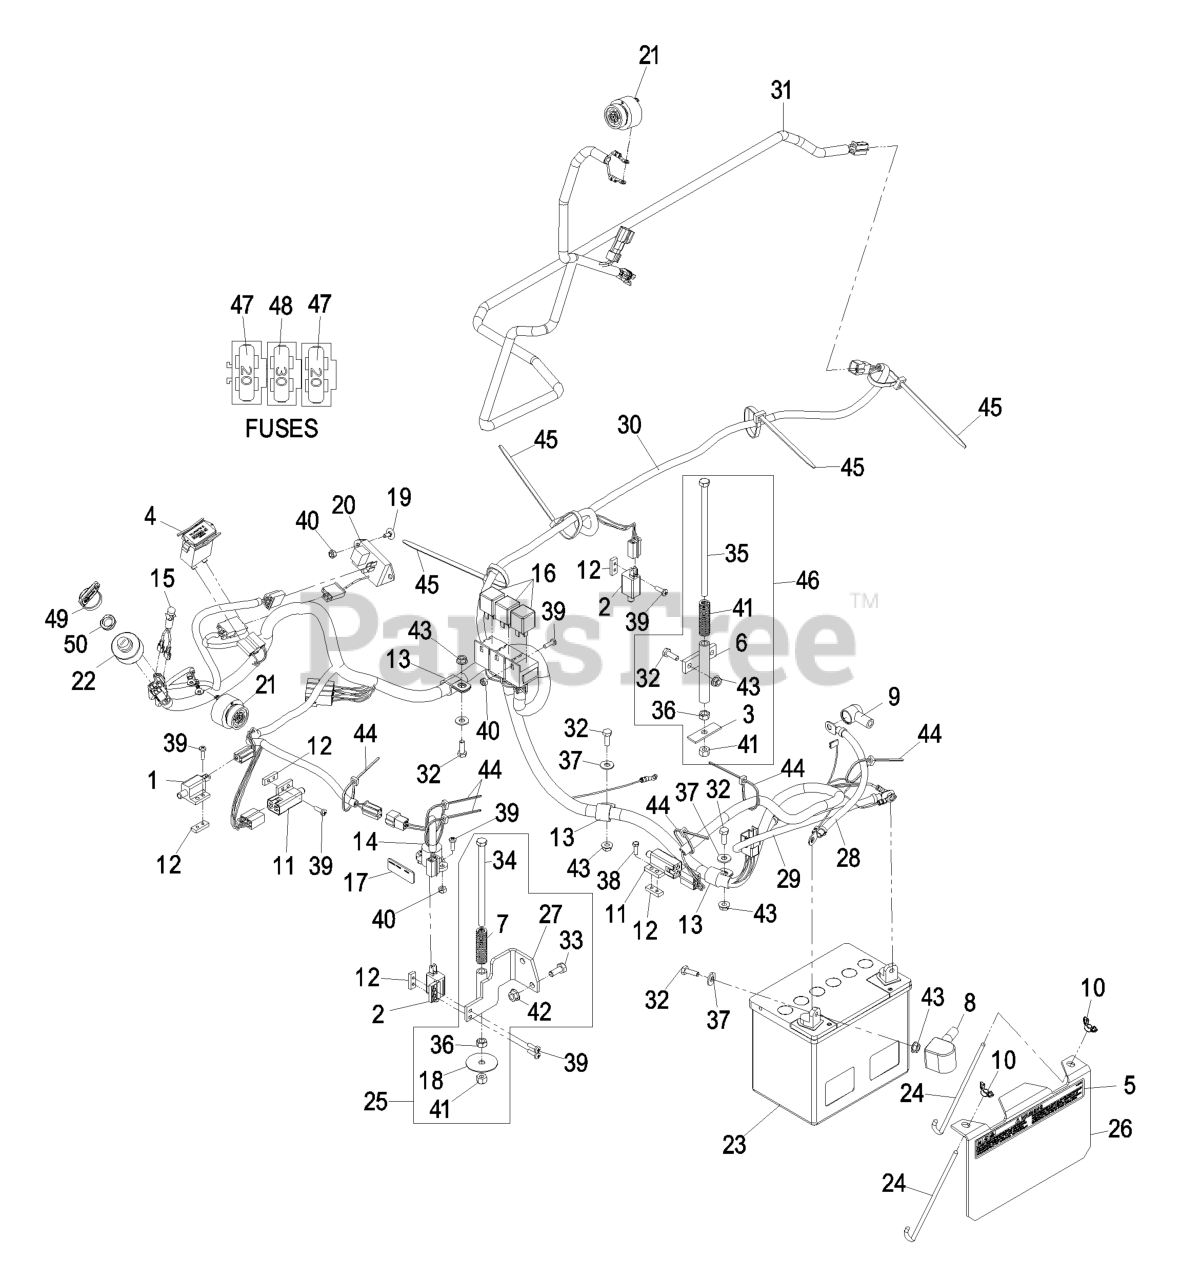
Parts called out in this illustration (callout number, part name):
1	SWITCH-OPEN, NORMALLY
2	SWITCH-CLOSED, NORMALLY
3	PLATE-SWITCH, SEAT
4	METER-HOUR
5	DECAL-BATTERY
6	MOUNT-SPRING, SEAT
7	SPRING-SWITCH, SEAT
9	INSULATOR-SOLENOID
10	WINGNUT
12	PLATE-TAPPED
13	CLIP-LOOM
15	INDICATOR-LED, RED
17	DECAL-SWITCH, MERCURY
19	BOLT-CARR
20	MODULE-DELAY, SEAT
21	ALARM-TONE, DUAL
24	BOLT-HOLDDOWN
25	ASM,SEAT SWITCH
27	WLD,SEAT SWITCH BRACKET
29	CABLE-BATTERY, NEGATIVE
30	HARNESS,WIRING
31	HARNESS-WIRE, HOPPER
32	SCREW-HH
33	SCREW-HH
34	BOLT-HH
35	SCREW-HH
36	NUT-HEX
37	WASHER-FLAT
39	SCREW-PPH
40	NUT-LOCK, NI
41	NUT-LOCK, NI
44	TIE-CABLE
45	TIE-PLASTIC
46	HOPPER SWITCH ACTUATOR AS
47	FUSE-BLADE TYPE, 20 AMP
48	FUSE-BLADE TYPE, 30 AMP
49	KEY-IGNITION
50	NUT-SWITCH, IGNITION
